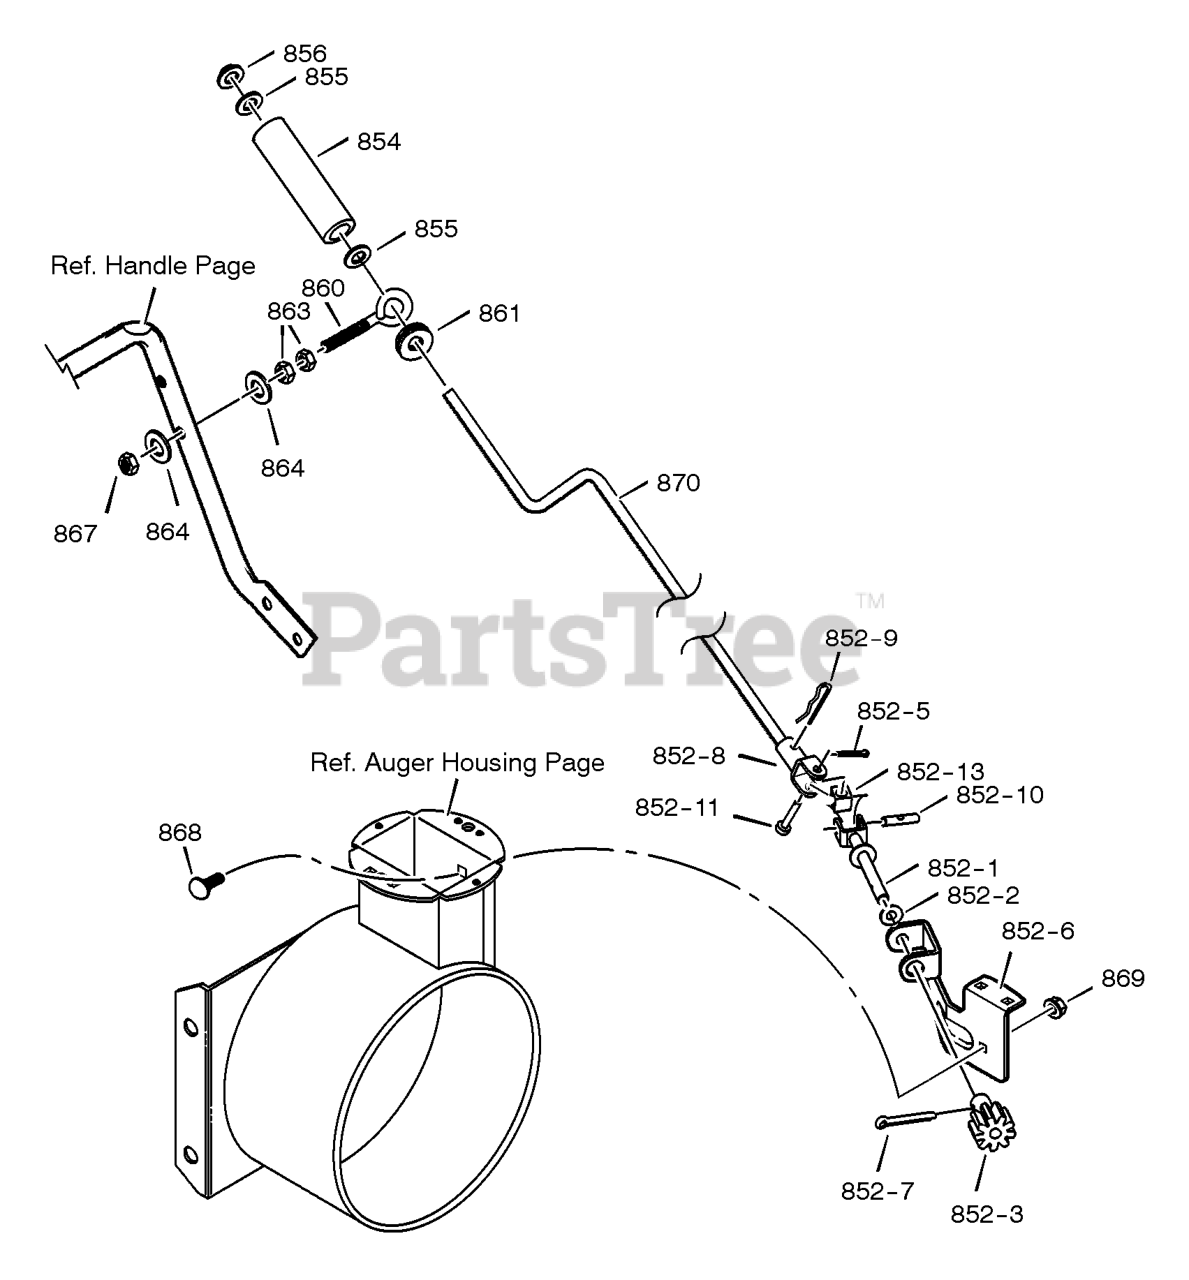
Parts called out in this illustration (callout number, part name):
852-1	ASSEMBLY, YOKE & ROD
852-2	WASHER, CURVED SPRING
852-3	GEAR, CHUTE ROTATION 9T
852-5	PIN, COTTER
852-6	BRACKET, GEAR MOUNT
852-7	PIN, COTTER
852-8	ASSEMBLY, YOKE ADAPTER YZ
852-9	PIN, HAIR
852-10	PIN, UNIVERSAL JOINT
852-11	PIN, CLEVIS
852-12	PIN, COTTER
852-13	HOUSING, UNIVERSAL
854	KNOB, SLEEVE
855	FLATWASHER
856	NUT, PUSH ON 3/8
860	EYE BOLT 3/8-16X6.00
861	GROMMET, EYE BOLT
863	NUT, 3/8-16 HEXJAM
864	FLATWASHER .406X.81X.066
867	NUT, 3/8-16 HEXNYL
868	BOLT, CARRIAGE 1/4-20 X 1.00
870	CRANK, ASSY CHUTE
